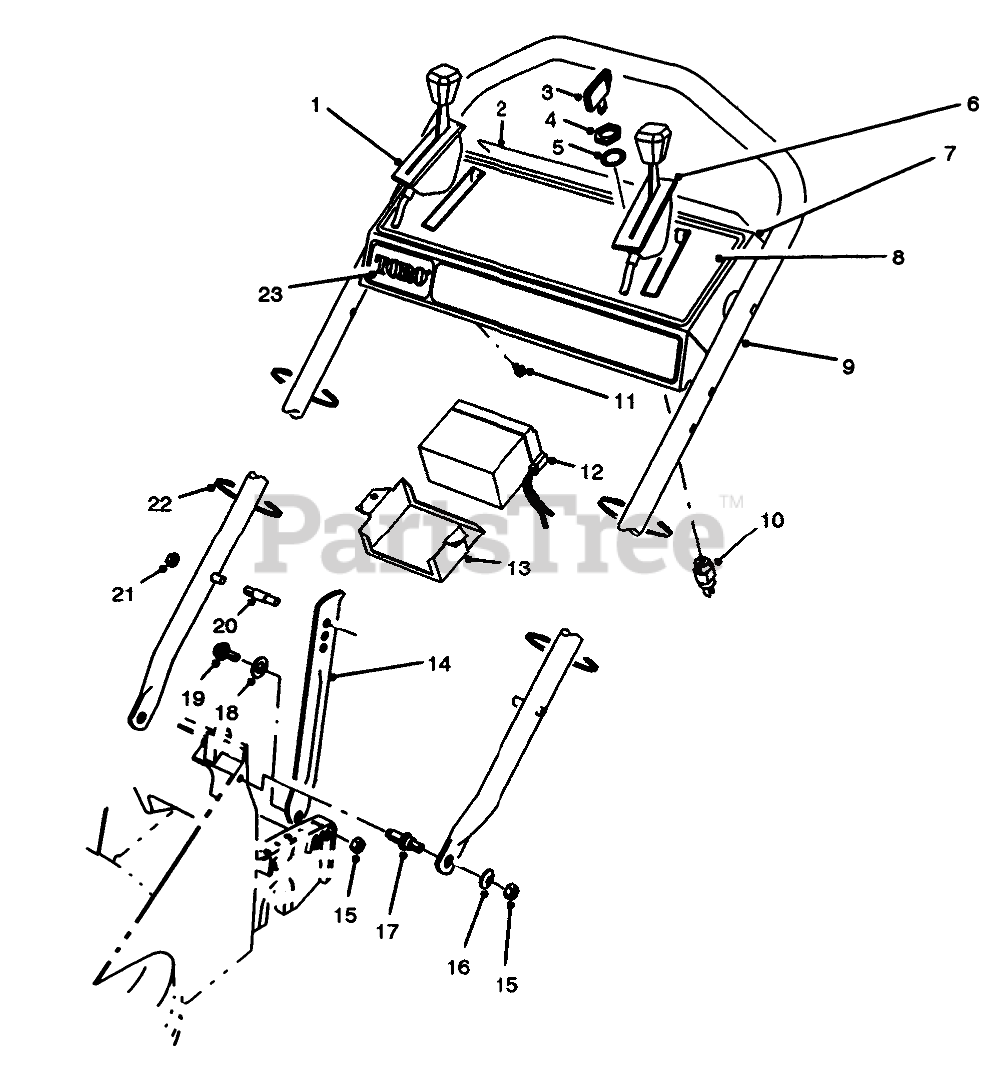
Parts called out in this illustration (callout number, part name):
1	Control-Ground Speed
2	DECAL - PANEL, REAR
3	KEY-IGNITION
4	NUT-HH
5	WASHER-TOOTH, INTERNAL
6	THROTTLE CONTROL
7	Panel-Control (Incl. Ref. #8)
8	DECAL - INSTRUCTION
9	UPPER HANDLE, PVC DIP
10	Switch-Starter (Incl. Ref. #4 & 5)
11	SCREW-HWHTF
12	BATTERY ASSEMBLY
13	Retainer-Battery
14	HANDLE LATCH
15	NUT-LOCK, NI
16	WASHER-PLAIN
17	SCREW - SHOULDER STUD
18	NYLON WASHER
19	SCREW-SHOULDER
20	HANDLE PIN
21	NUT-LOCK, NI
22	TIE-CABLE
23	DECAL - KEY LECTRIC
